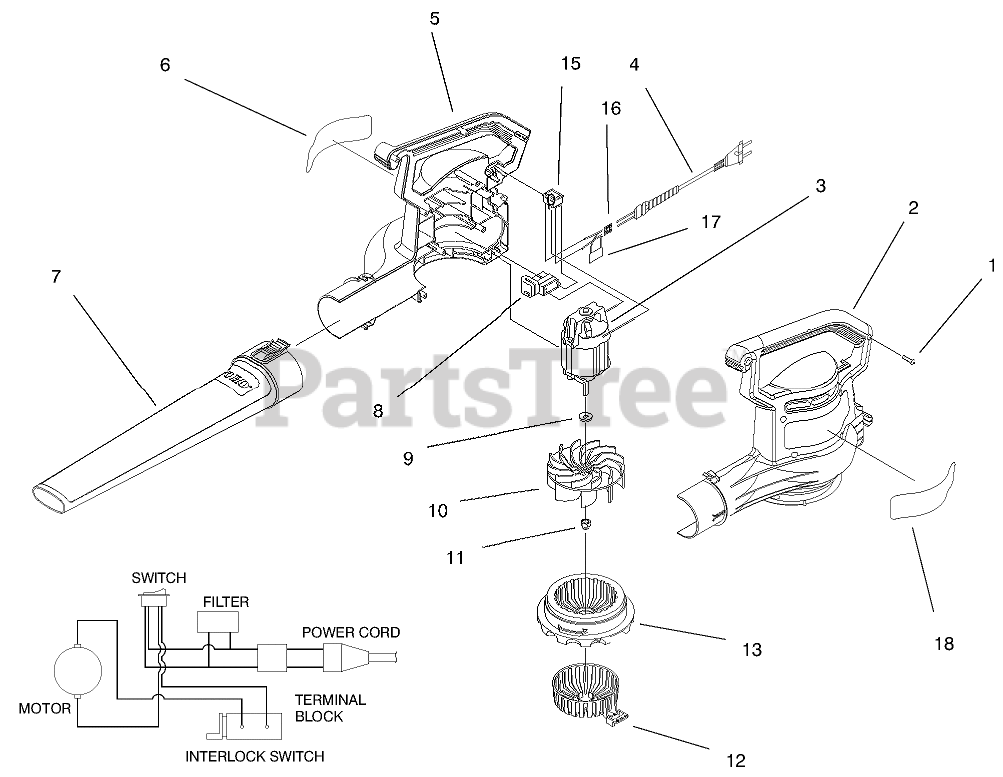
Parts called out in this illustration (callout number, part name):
1	SCREW-PPH
3	MOTOR, 230V SUPER BLOWER
5	HOUSING, RH - 230V BLOWER
9	WASHER-FLAT
10	IMPELLER, BLOWER
12	CHOKE - AIR, RED
13	COVER - INLET, W/HOLE
17	FILTER - RFI
